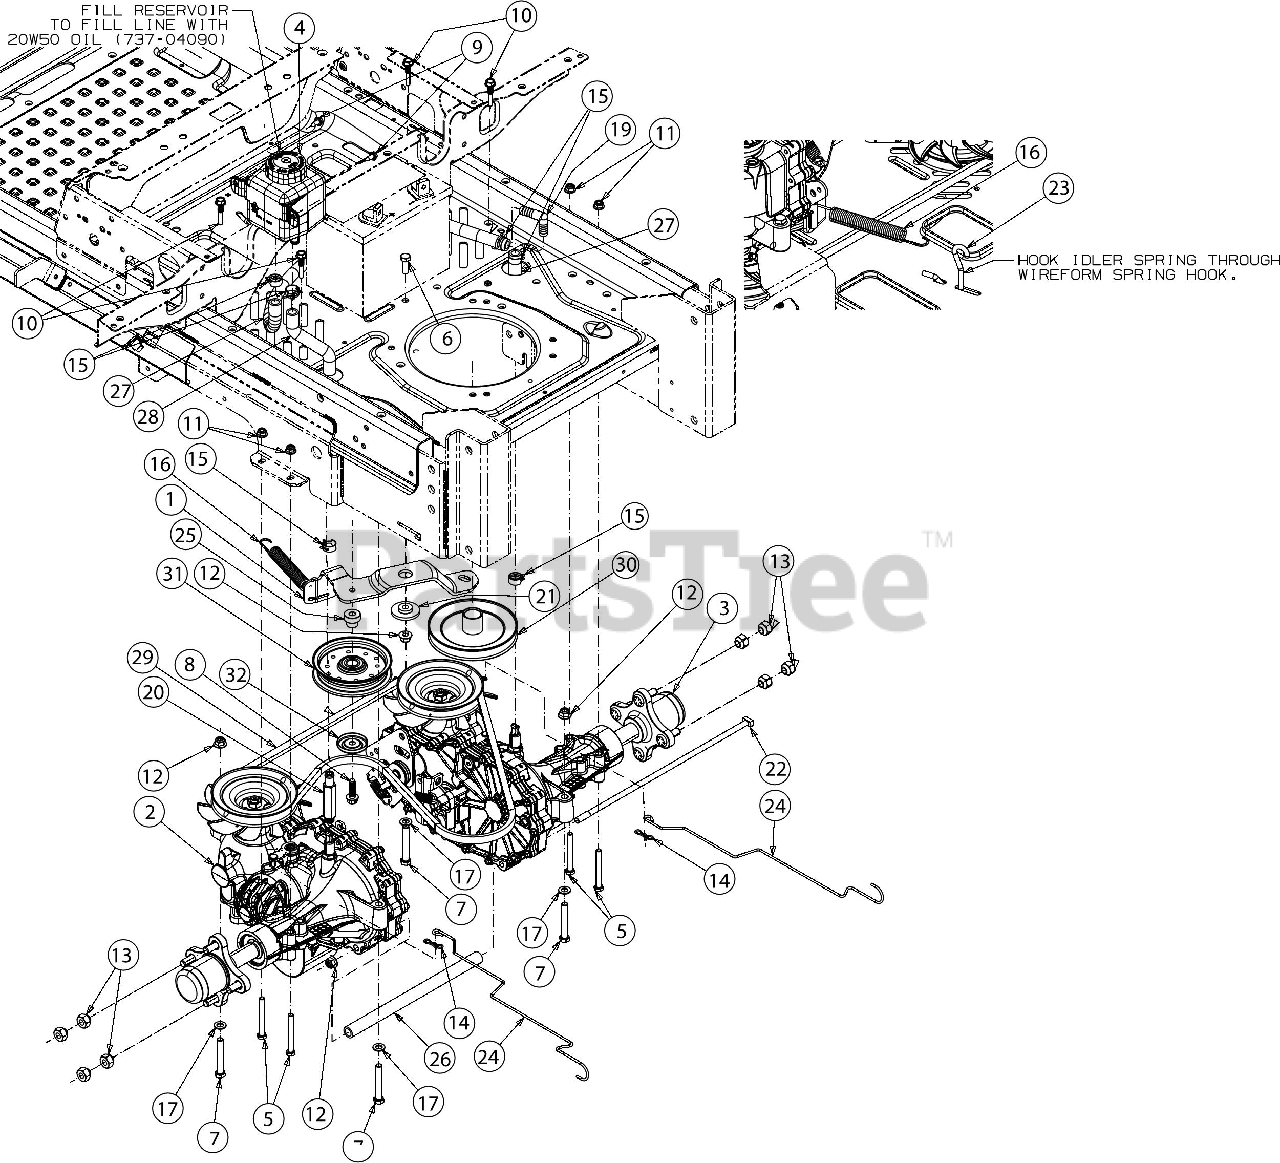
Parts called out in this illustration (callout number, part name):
1	IDLER BRACKET ASSEMBLY
2	TRANSMISSION ASSEMBLY (LH)
3	TRANSMISSION ASSEMBLY (RH)
4	HYDRAULIC TANK
5	HEX SCREW 5/16-18 X 2.75
6	SCREW 3/8-16 X 1 GR5
7	HEX SCREW-3/8-16X2.5 GR5
8	SCREW 3/8-16 X1.250
9	SCREW 1/4-20X.625
10	BELT KEEPER ROD .25 X 1.585
11	FLANGE LOCK NUT 5/16-18
13	LUG NUT 7/16-14
14	BOW TIE COTTER PIN 1/4-5/16
15	FUEL HOSE CLAMP
16	EXTENTION SRING .75 DIA. X 6.85
17	FLAT WASHER
19	90 DEGREE NYLON FITTING
20	EXTENSION FITTING 9/16-18
21	SHOULDER SPACER
22	SUPPORT TUBE ROD
23	IDLER SPRING HOOK
25	SHOULDER SPACER
26	TRANSMISSION SPACER .75OD X 11.31
27	FUEL LINE 1/2 ID"
28	EXPANSION HOSE
29	TRANSMISSION DRIVE BELT A X 67
30	ELECTRIC PTO PULLEY
31	IDLER PULLEY 4.25 DIA
32	IDLER PULLEY CAP
